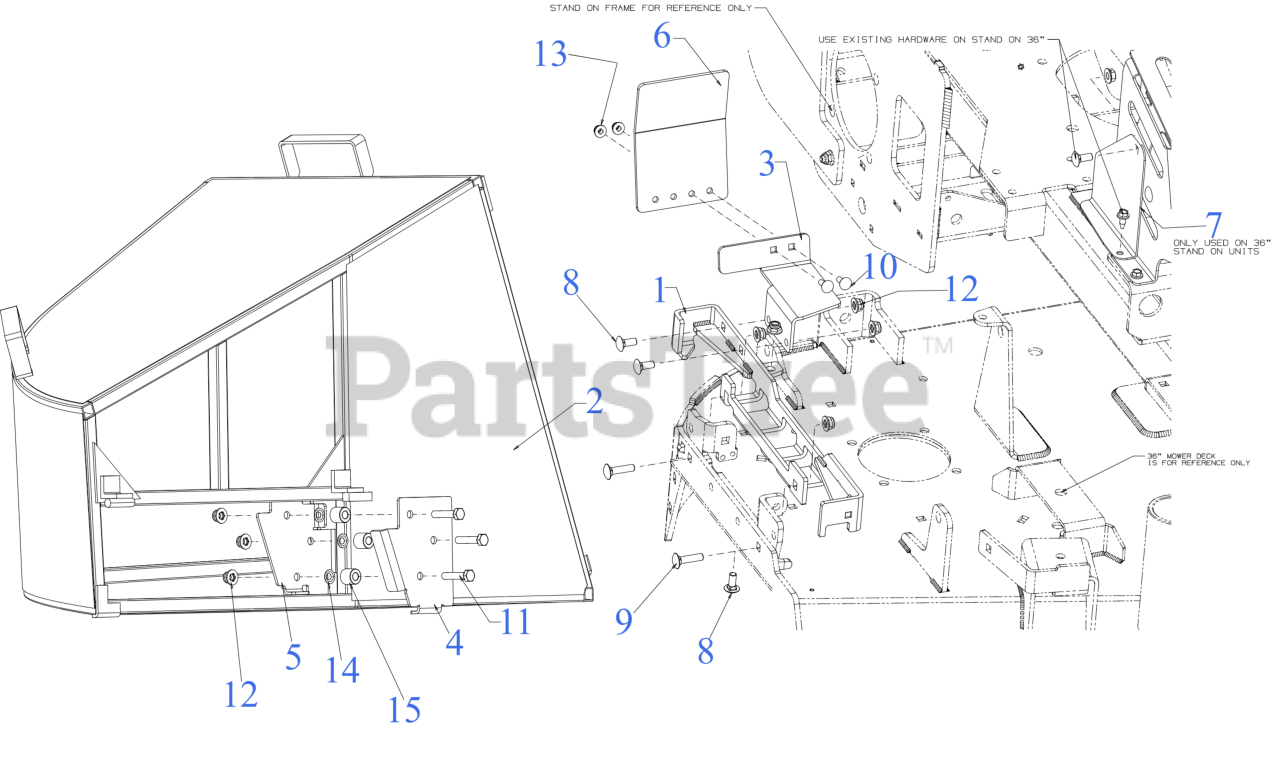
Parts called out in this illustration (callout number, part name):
1	MOUNT BRACKET
2	GRASSBAG
3	DEFLECTOR CHUTE BRACKET
4	OUTER BAG BAFFLE
5	INNER BAG BAFFLE
6	DEFLECTOR BRACKET
8	CARRIAGE BOLT 5/16-18 x .75
9	CARRIAGE BOLT 5/16-18 x 1.25
10	SCREW 1/4-20 x .75 GR5
11	SCREW 5/16-18 x 1.5 LG
12	FLANGE LOCK NUT 5/16-18
13	FLANGE LOCK NUT
15	SPACER .34 x .75 x .63 LG
